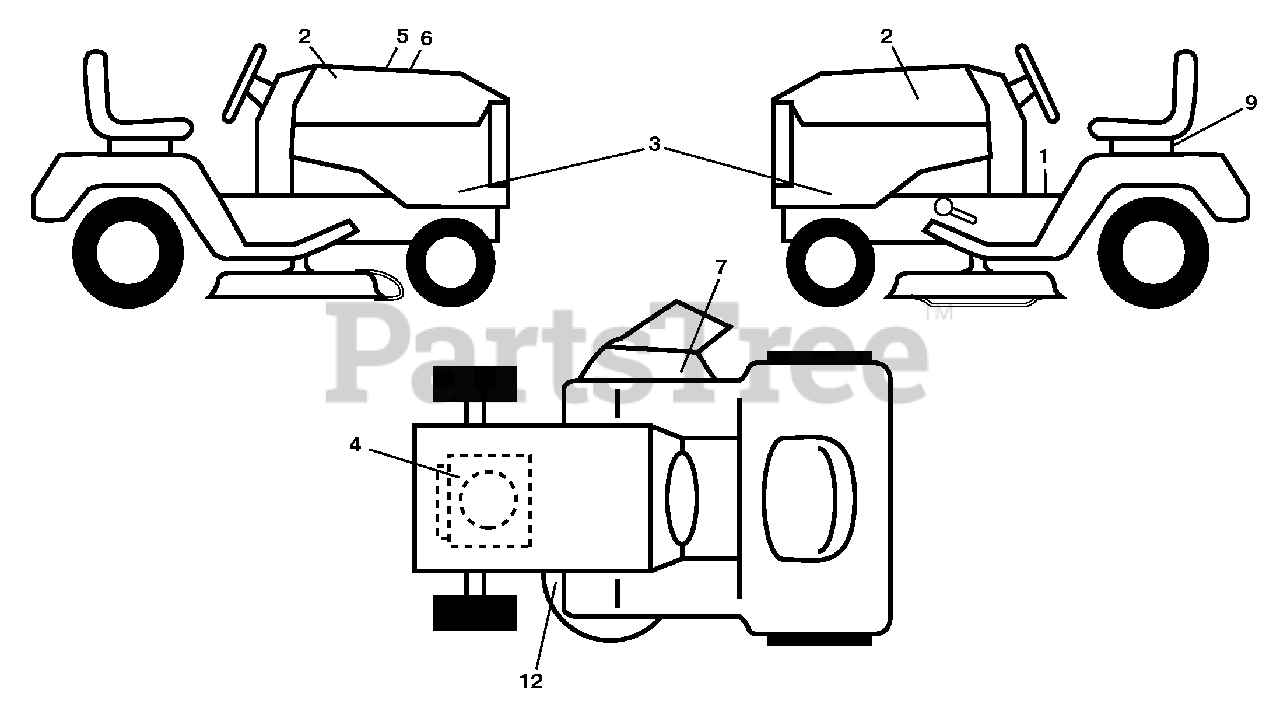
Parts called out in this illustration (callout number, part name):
1	Decal, Fender Warning
2	Decal, Hood
3	Decal, Hood Panel SD
4	Decal, Engine H.P.
5	Decal, Customer Respons.
6	Decal, Replacement
7	Decal, Mower Warn. Keep Hands Away
9	Decal, Battery Dnge/Poi
12	Decal, Mower V-Belt Schematic
